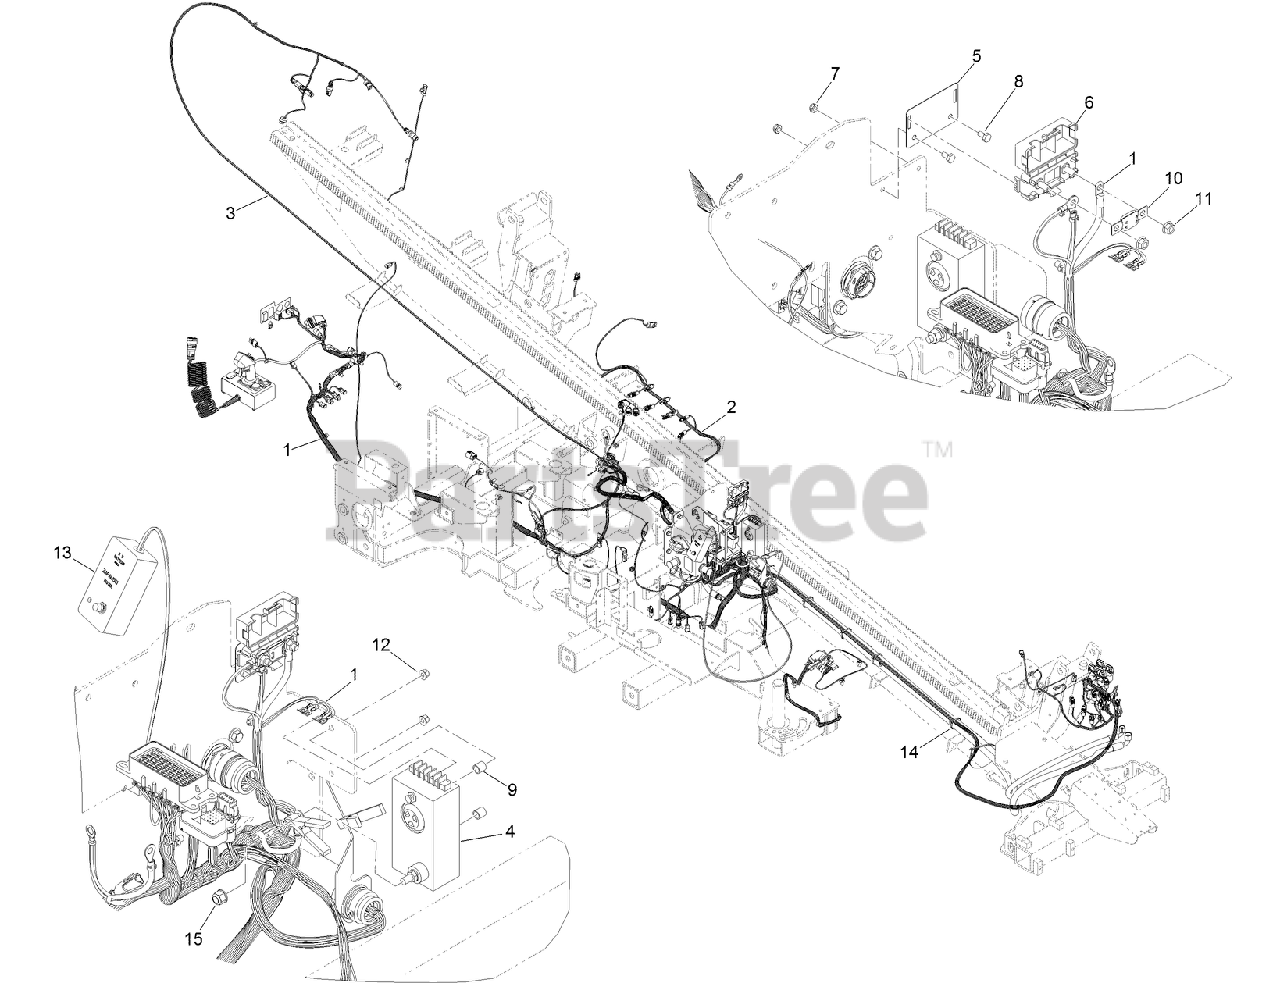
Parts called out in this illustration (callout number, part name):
1	HARNESS-WIRE
2	HARNESS-WIRE
3	HARNESS-WIRE
5	BRACKET-FUSE
6	HOLDER-FUSE, MEGA
7	NUT-LOCK, NI
8	SCREW-HH
9	SPACER
10	FUSE-MEGA
11	NUT-HF
12	NUT-FLANGE, NI
13	TESTER-ZAPALERT
14	TIE-CABLE
15	NUT-LOCK, NI
